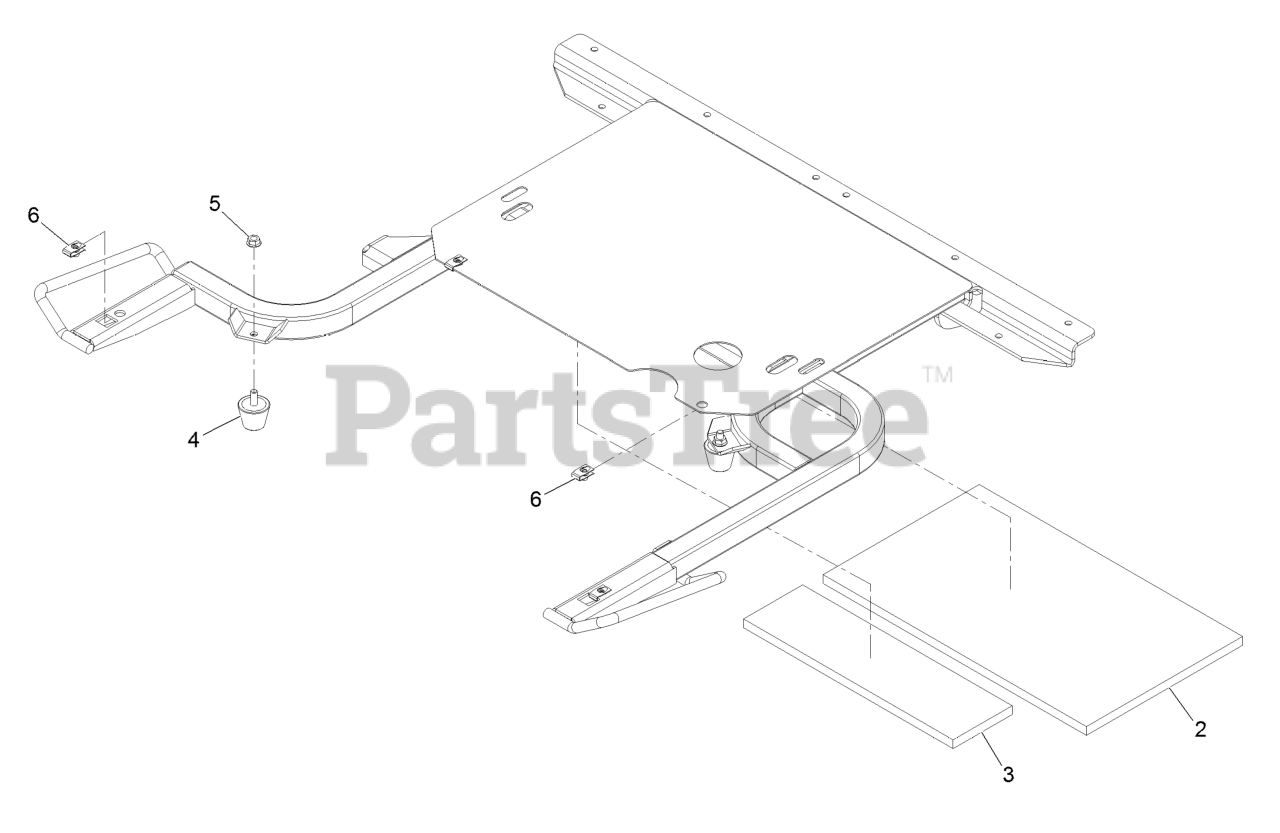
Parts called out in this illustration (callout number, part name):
2	INSULATION-FOAM PAD, REAR
3	INSULATION-FOAM PAD, FRON
4	BUMPER-RUBBER
6	Nut-Retainer-Panel 1/4-20
